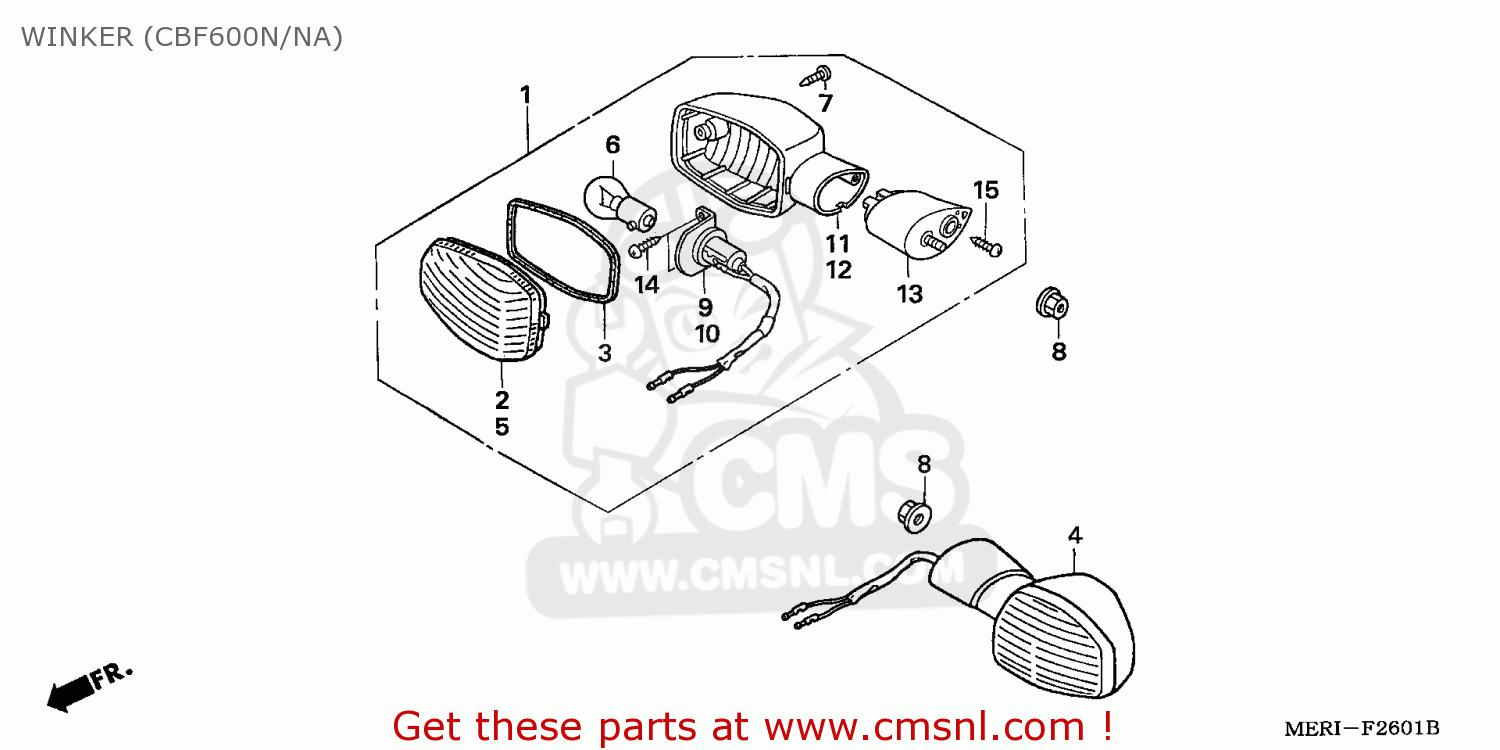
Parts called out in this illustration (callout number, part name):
1	WINKER ASSY,R FR
2	LENS WINKER R
3	PACKING LENS
4	WINKER ASSY,L FR
5	LENS WINKER L
6	BULB,WINKER
7	SCREW TAPPING,4X1
8	NUT,FLANGE,6MM
